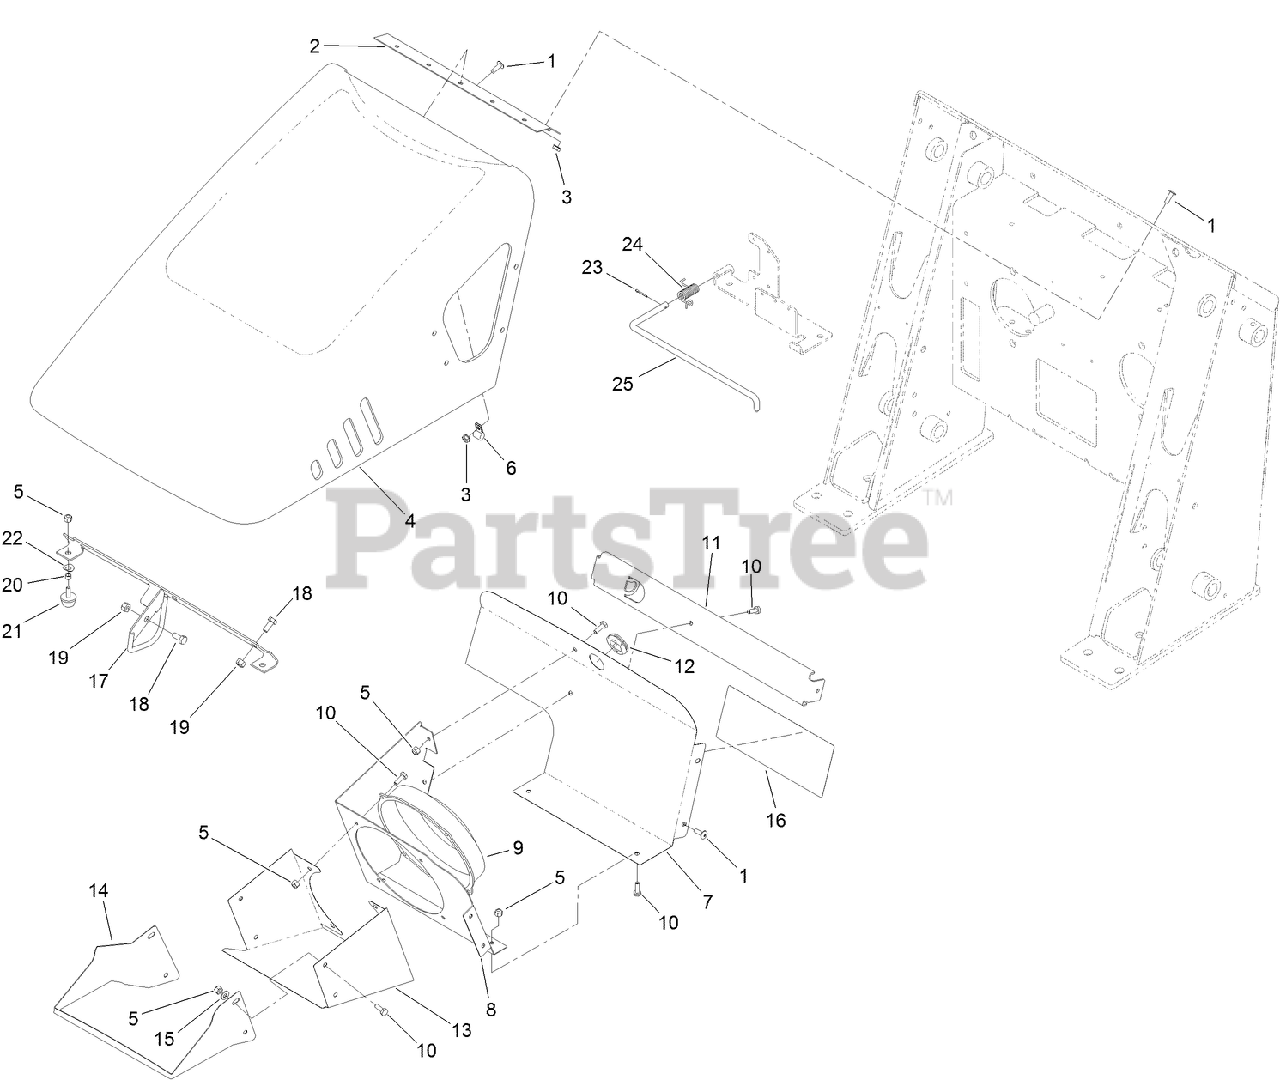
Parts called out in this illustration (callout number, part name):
1	SCREW-HEAD, TRUSS
2	HINGE-HOOD
3	NUT-HF
5	NUT-LOCK, NI
6	CLAMP
7	BRACKET-FAN, BACK
8	BRACKET-FAN, BACK
10	SCREW-HH
11	BRACKET-SUPPORT, HOOD
12	GROMMET
13	SHROUD-FAN
14	SHROUD-FAN, FRONT
15	WASHER-FLAT
16	DECAL-SERVICE
17	LATCH-ROD
18	SCREW-HH
19	NUT-LOCK, NI
20	SPACER
21	BUMPER
22	WASHER-SPRING
23	PIN-COTTER
24	Spring-Torsion
25	Rod-Support, Hood
